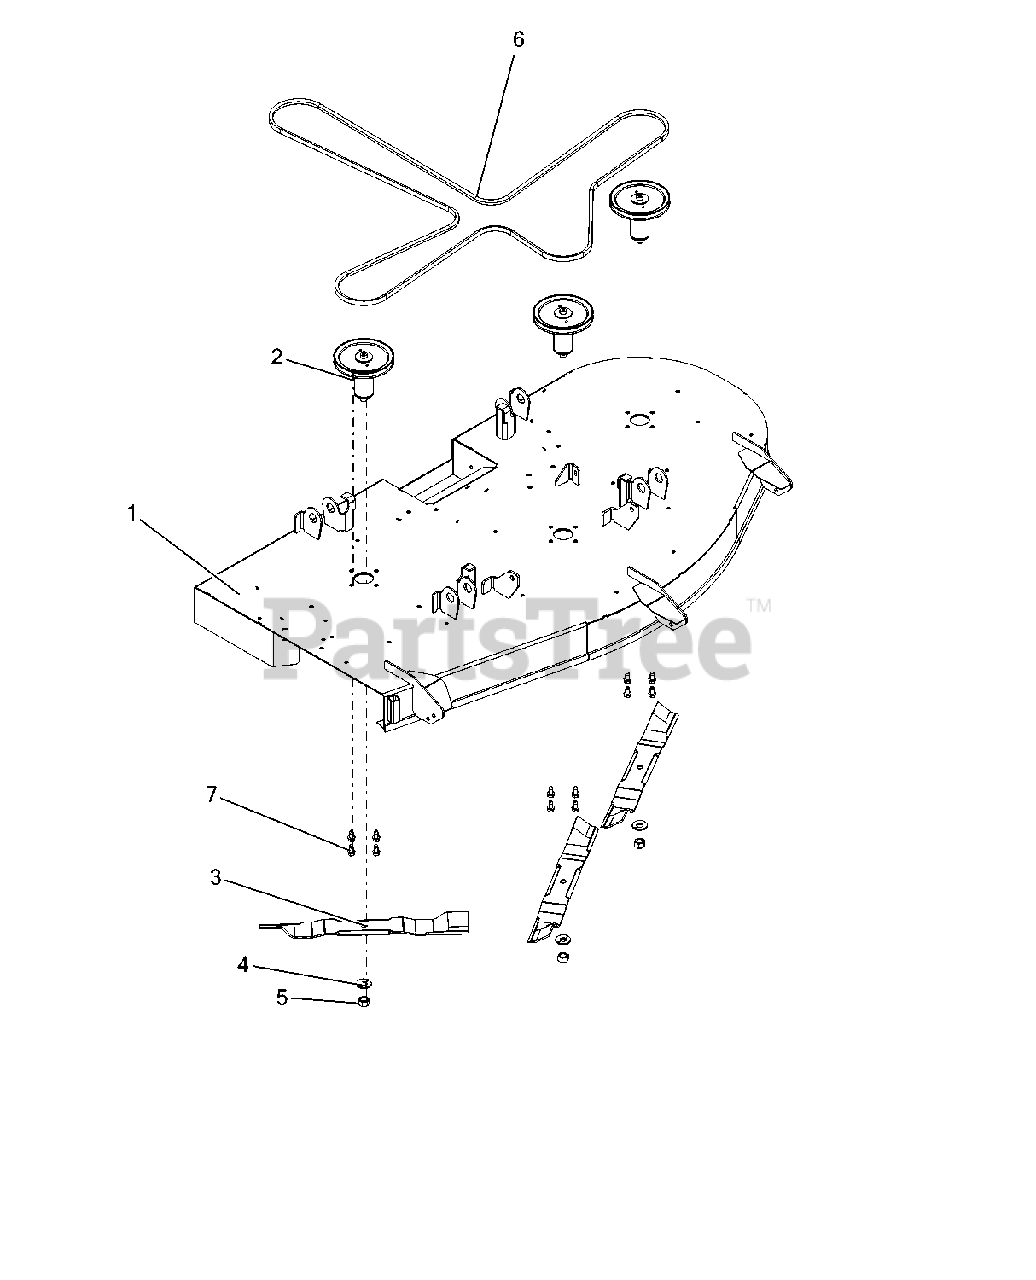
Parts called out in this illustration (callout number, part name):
1	WLDMT, MOWER DECK - 60" WITH DECALS
2	ASM, SPINDLE 4.75" DIA.
3	BLADE, 21" - 35 DEG
4	WSHR, BLVL .63X1.625X.14
5	NUT-HEX .62-18 YWZC
6	V-BELT, HA SECTION
7	SCR-TAP .38-16X.75 HWH TR YWZ
